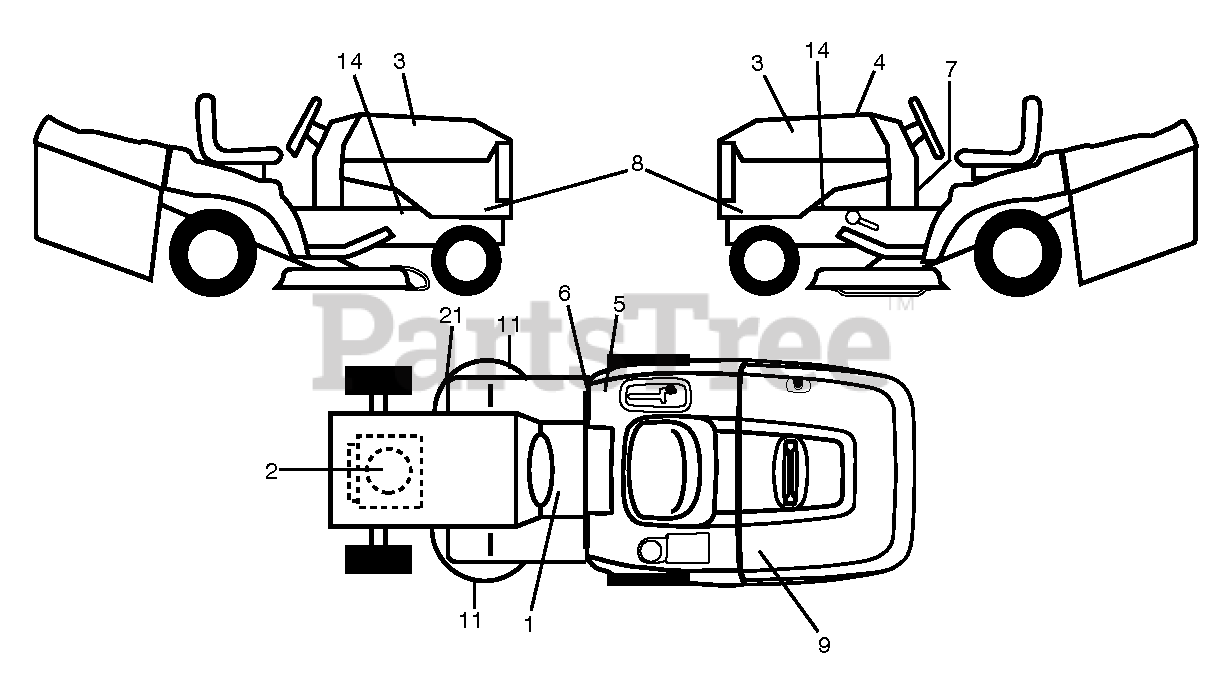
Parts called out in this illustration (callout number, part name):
1	DECAL.WARNING.COMBINED.T/CRD
2	DECAL.ENGINE.WARNING
3	RP.DECAL.BADGE.170MM.TEXTLOGO
4	DECAL.RPL.KW.FS541.TCRD.107R
5	DECAL.PEDALS.SYMBOL
6	Decal, Certification 6MIL 100D
9	Decal, Warning CRDBAGGER ELECDUMP
11	DECAL.CUTFINGER.CE.02
14	DECAL.CHASSIS.HOT.MUFFLER
21	DECAL DECAL V-BELT 97 CM CRD
